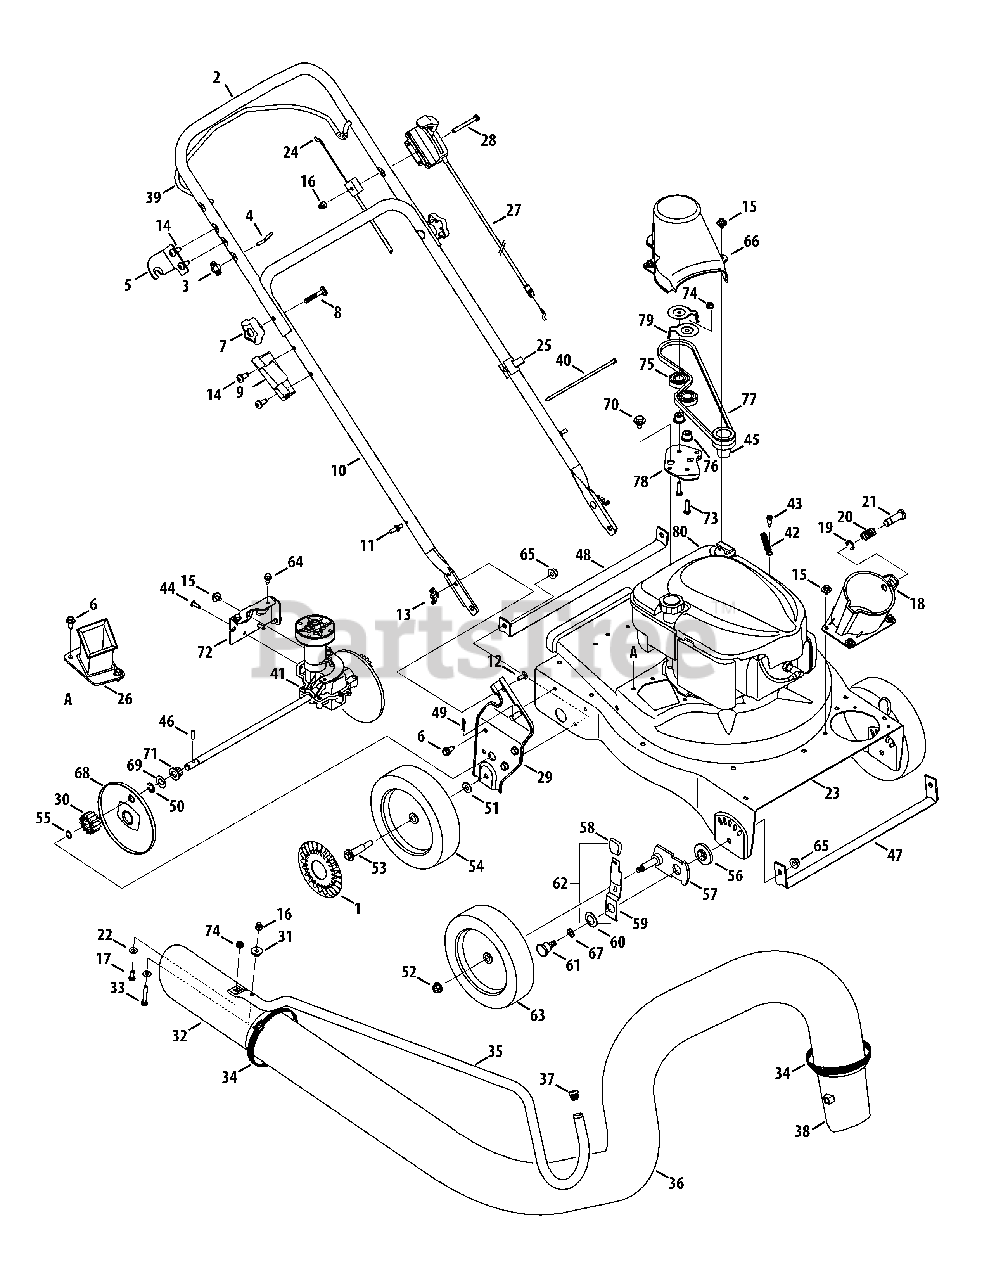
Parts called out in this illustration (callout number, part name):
1	Hub Cap
2	Upper Handle
4	Eye Bolt
5	Upper Handle Bracket
6	Hex Cap Screw 5/16-12 x.750
7	Handle Knob 5/16-18
8	Carriage Bolt
9	Nozzle Handle Clip
10	Lower Handle
11	Studs
12	Carriage Screw 1/4-20 x.75
13	Wing Nut 1/4-20
14	TT Screw, 5/16-18 x .750
15	Screw, 1/4-20 x .500
16	Cap Lock Nut, 1/4-20
17	Hex Cap Screw 1/4-20 x.620
18	Hose Base Adapter Assembly
19	E Ring.500 Dia
20	Compression Spring
21	Clevis Pin
22	Flat Washer.271 ID x.630 OD
23	Upper Flail Housing
24	Drive Control Cable
25	Cable Guide
26	Chipper Chute Assembly
27	Speed Control Cable
28	Hex Screw, 1/4-20 x 2.50
29	Handle Bracket Ass’y RH
30	Spur Gear - RH
31	Spacer
32	Hose Nozzle
33	Hex Cap Screw 1/4-20 x 2.625
34	Adjustment Clamp
36	Vacuum Hose
37	Handle Plug
38	Hose Adapter
39	Drive Control
40	Cable Tie
41	Transmission Assembly
42	Extension Spring,.375 x 2.95
43	Shoulder Screw, #12-24 x .30 x .46
44	Screw, #12-16 x .750
45	Impeller Hub
46	Dowel Pin
47	Front Wheel Support Brace
48	Rear Wheel Support Brace
49	Cotter Pin
50	E-Ring
51	Flat Washer, .406 x .875 x .105
52	Nut, Flglk., 3/8-16
53	Shoulder Screw, .496 x 1.605
54	Rear Wheel
55	Snap Ring
56	Height Adjustment Bearing
57	Pivot Arm Assembly
58	Height Adjustment Knob
59	Spring Lever
60	Bell Washer.760 ID x.25 OD
61	Shoulder Screw,.750 x.500
62	Height Lever Assy (Incl. Ref.# 58-59)
63	Front Wheel
64	Screw, 1/4-20 x .625
65	Flange Lock Nut, 3/8-16
66	Belt Cover
67	Thrust Washer.375 ID x.70 OD
68	Wheel Cover
69	Flat Washer,.508ID x1.00OD x.020
70	Shoulder Screw,.560 x.165
71	Drive Axle Bushing
72	Transmission Mounting Bracket
73	Screw, 1/4-20 x 1.00
74	Flange Lock Nut, 1/4-20
75	Ball Bearing
76	Flange Spacer,.260 x.659 x.517
77	Belt, 3/8 x 32.5
78	Idler Bracket
79	Belt Keeper
80	Engine 126M02-0434-F1
